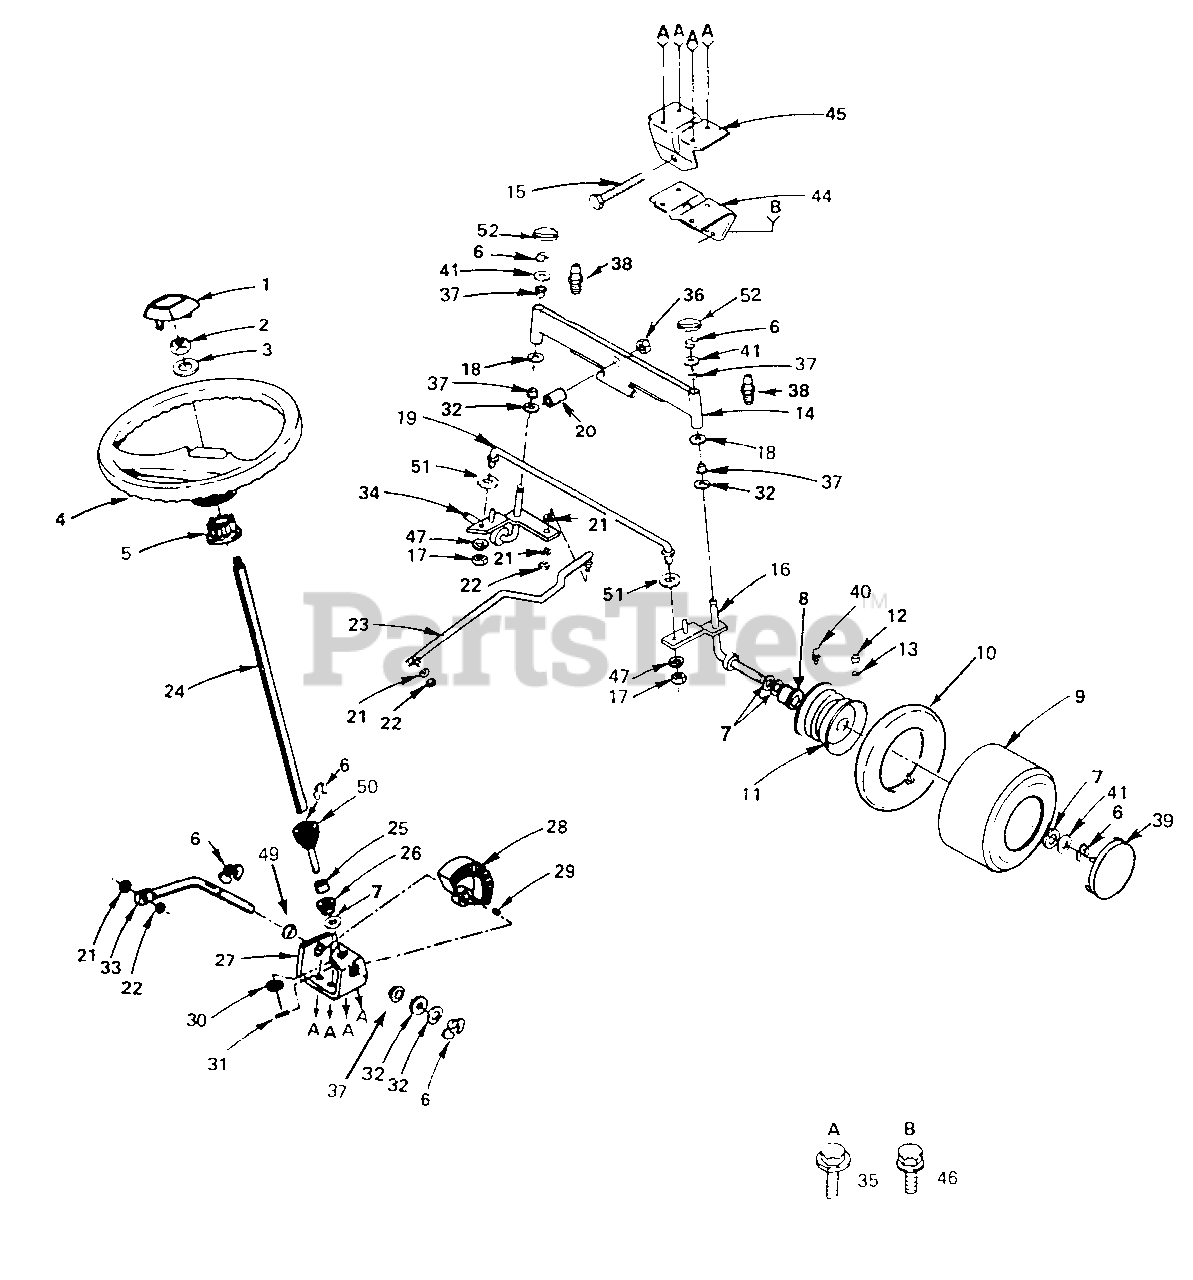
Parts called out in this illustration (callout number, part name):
1	Insert, Steering Wheel
2	Nut, Hex Toplock Jam 1/2-20
3	Washer, 17/32 x 2-1/4 x .160
4	Steering Wheel, 13"
5	Adapter, Wheel, Steering
7	Washer, 25/32 x 1 1/4 x 16 Ga.
8	Bearings, Wheel, Front
9	Tire, Rib Tread 15 x 6.00-6 (Tubeless)
10	Tube, Tire
11	Rim Assembly, 6 Front
12	Stem, Valve
13	Cap, Valve
14	Axle Assembly, Front
15	Bolt, Hex 5/8-11 x 3-3/4
16	Spindle Assembly, R.H.
17	Nut, Hex 5/16-24
18	Washer, 27/32 X 1-1/4 X 16 Ga.
19	Tie Rod
20	Bearing, Spacer
21	Lockwasher, 3/8
22	Nut, Hex 3/8-24
24	Shaft Assembly, Steering
26	Bushing, Steering Rod
27	Bracket Assembly, Steering
28	Gear, Sector
29	Woodruff Key, 3/16 x 3/4
30	Washer, Hardened
31	Drive Pin, 3/16 X 1
32	Bearing, Thrust
33	Rod, Steering
34	Spindle Assembly, L.H.
35	Screw, Special
36	Nut, Lock Flange, 5/8-11
38	Fitting, Grease
39	Cover, Wheel, 6", Front
40	Grease Fitting
41	Washer, 25/32 x 1-5/8 x 16 Ga.
44	Support, Saddle, Front
45	Support, Saddle, Rear
46	Screw, Hex Washer Thd. Rolling - 5/16-18 X 1/2
47	Lockwasher, 5/16
49	Nyliner, Snap In
50	Gear, Pinion
51	Washer, 11/32 X 3/4 X 16 Ga.
52	Spindle Cap
